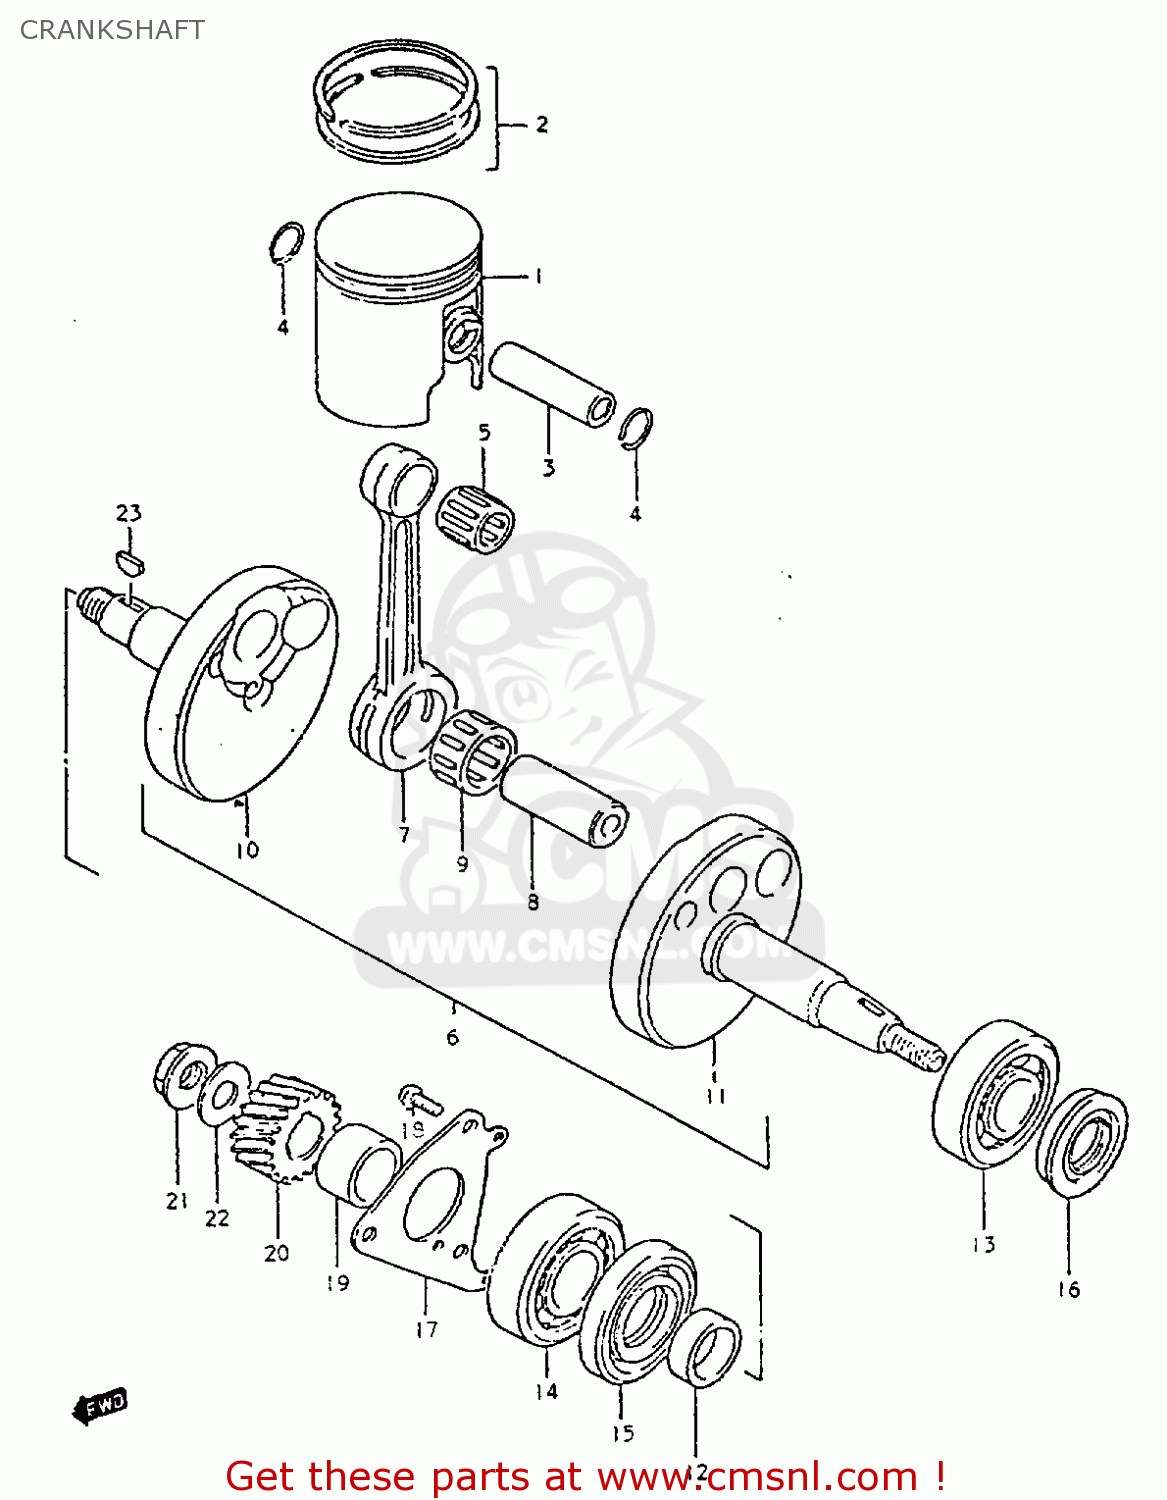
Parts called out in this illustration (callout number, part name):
1	PISTON
2	RING SET,PISTON
3	PIN,PISTON
4	RING,SNAP
5	BEARING
6	CRANKSHAFT ASSEMBLY
7	CONNECTING ROD
8	PIN,CRANK
9	BEARING
10	CRANKSHAFT,RIGHT
11	CRANKSHAFT,LEFT
12	SPACER(20X26X9)
13	BEARING
14	BEARING
15	OIL SEAL
16	SEAL,OIL(19.6X37X8)
17	RETAINER,CRANKSHAFT BEARING,R
18	SCREW 6X12
19	SPACER(20X26X14)
20	GEAR,PRIMARY DRIVE NO.19
21	NUT
22	WASHER
23	KEY
